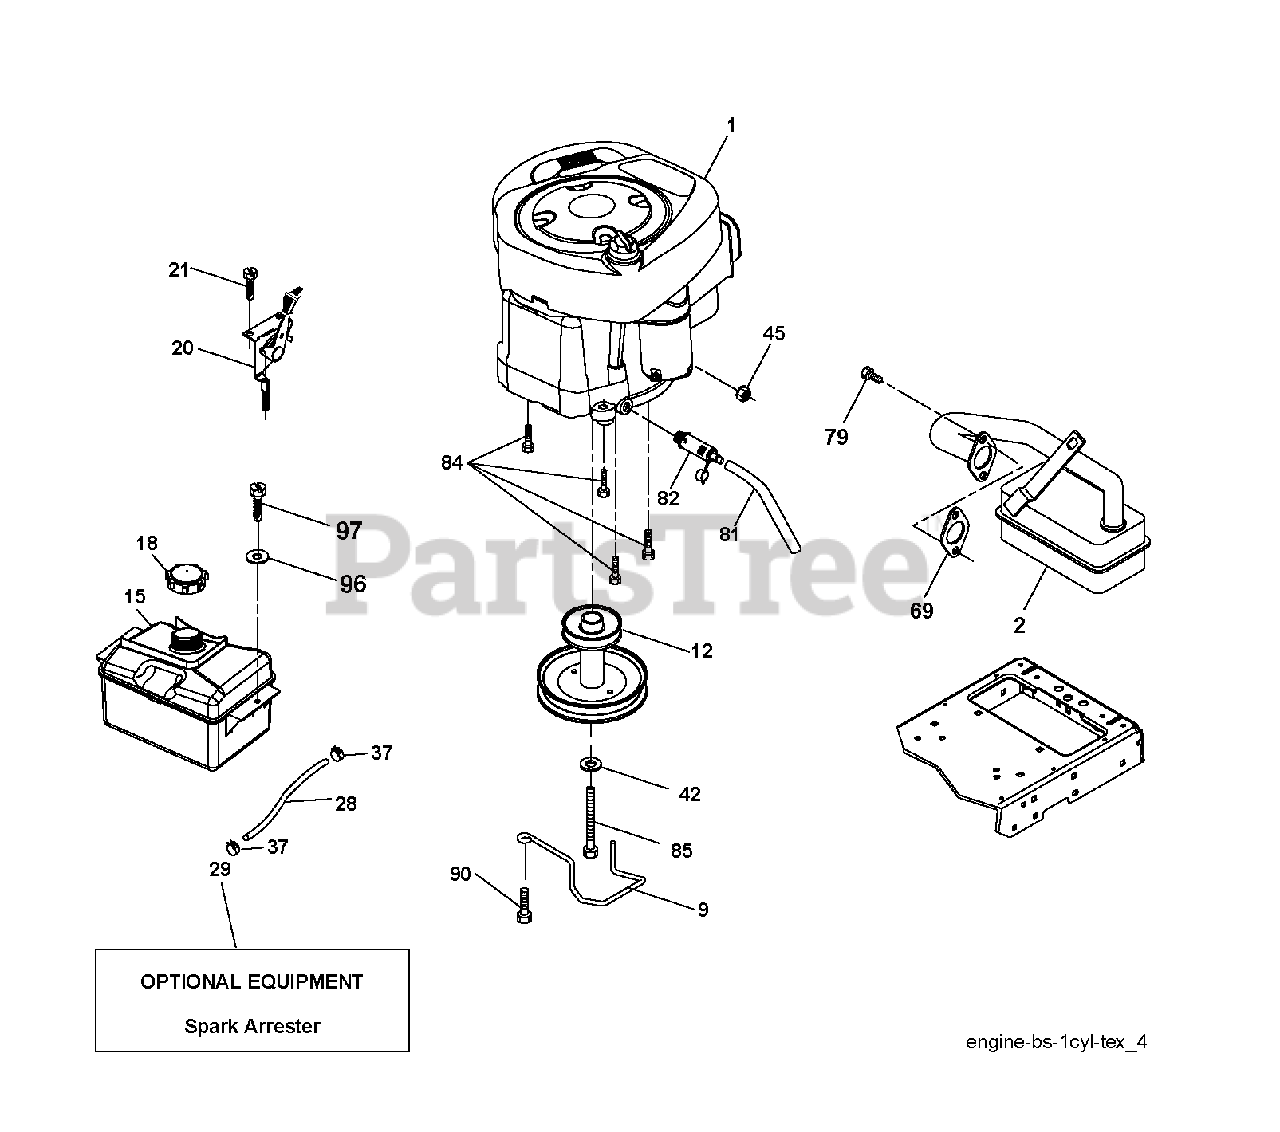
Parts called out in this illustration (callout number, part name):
9	KEEPER.BELT.ENGINE.3.25
12	PULLEY ENGINE
15	TANK FUEL FRT 1.5 GAL
18	CAP.FUEL.2.25"VENTED"
20	CONTROL.TH/CK.C.
21	SCREW.#10 X 0.750.BOS THREAD
28	LINE.FUEL.20
29	ARRESTER SPARK (OPTIONAL)
37	HOSE CLAMP
42	LOCKWASHER
45	NUT
69	REPL BY 532 27 22-93
79	SCREW.SOCKET HD.5/16-1
81	TUBE, DRAIN OIL ASM.
82	VALUE.OIL.DRAIN
84	SCREW.3/8-16
85	BOLT
90	SCREW 3/8-16X1
97	SCREW HEXWSHR 1/4-20X3/4
